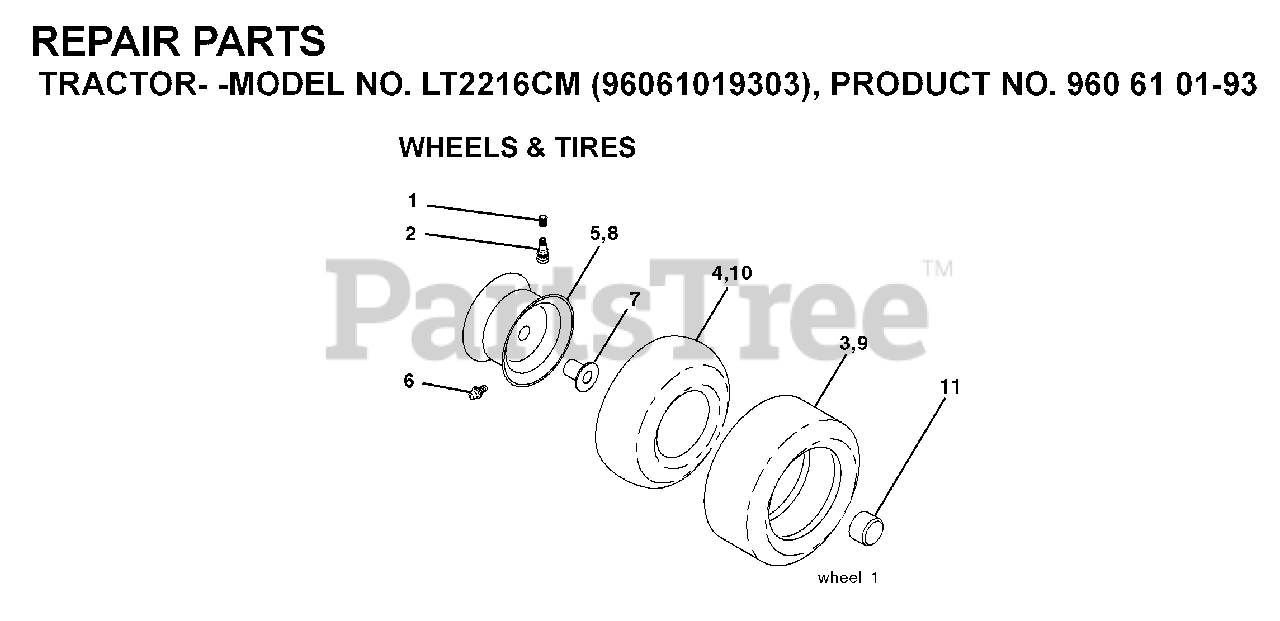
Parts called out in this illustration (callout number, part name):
1	VALVE CAP
2	VALVE STEM LT
3	TIRE HEAVY DUTY
4	TUBE.5.3/4.5/6
5	RIM ASM 6" FRONT SILVER
6	FITTING LT
7	BEARING T
8	RIM ASM 8" REAR SILVER
9	TIRE HEAVY DUTY
10	TUBE
11	CAP, AXLE BLK
